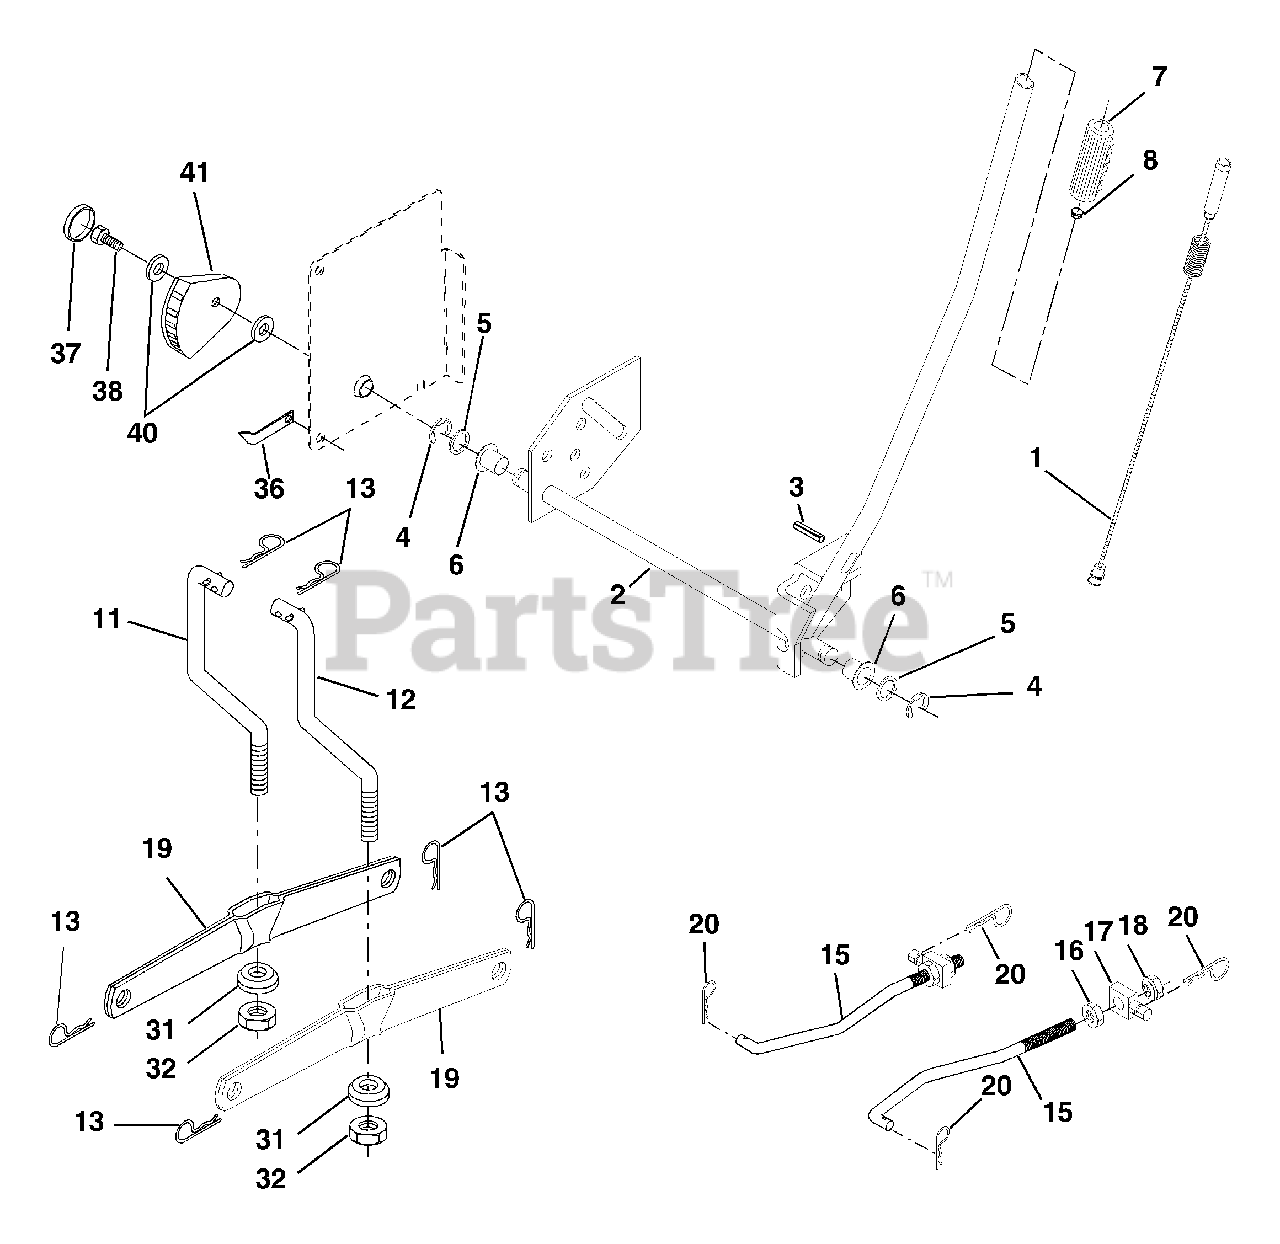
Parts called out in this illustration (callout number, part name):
1	Wire Asm Inner/Sprg W/plunger LT
2	Shaft Asm Lift RH w/Inf
3	Pin Groove 1 500 Zinc
4	E Ring #5133-62
5	Washer 21/32 X 1 X 21 Ga
6	Bearing Nylon Blk 629 Id
7	Grip Handle
8	Button Plunger
11	Link Lift LH Fixed Length
12	Link Lift RH Fixed Length
13	Retainer Spring
15	Link Front
16	Nut Jam Hex 1/2-13 Unc
17	Trunnion
18	Nut Lock W/Wsh 1/2-13 Unc
19	Arm Suspension Rear
20	Retainer Spring
31	Bearing Pvt Lift
32	Nut Crownlock 3/8 - 24
36	Pointer Height Indicator
37	Plug Hole Blk 1.485/1.515 Dia.
38	Screw 5/16-18 x 1
40	Washer 11/32 x 1-1/2 10 Ga.
41	Indicator Height STLT
